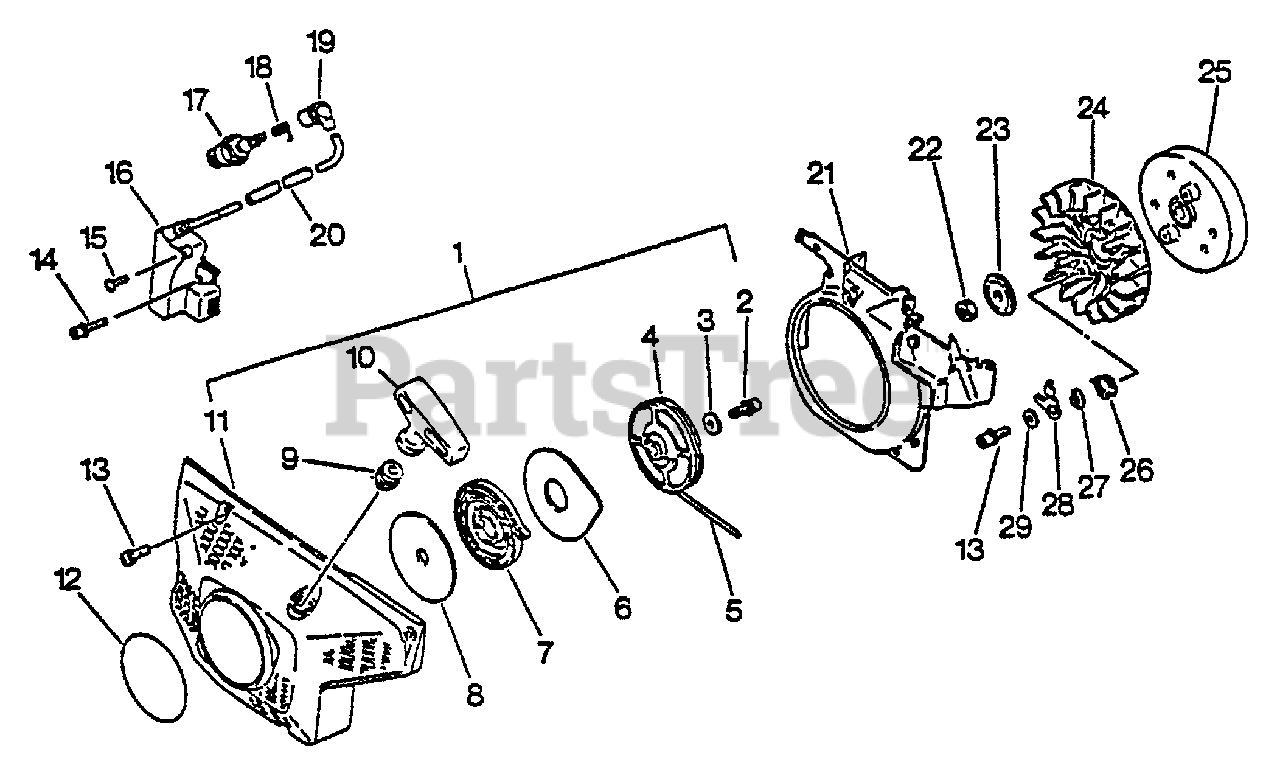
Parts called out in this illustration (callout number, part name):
1	STARTER ASSY
2	SCREW - 5X14
3	WASHER - 5
4	REEL, ROPE
5	ROPE, STARTER - 4X950
6	PLATE, STARTER
7	SPRING, REWIND
8	PLATE, STARTER
9	GUIDE, ROPE
10	GRIP, STARTER
11	CASE, STARTER
12	LABEL - ECHO
13	SCREW - 5X20
14	SCREW - 4X20
15	SCREW - 4X8
16	COIL, IGNITION
17	SPARK PLUG -- BPM-6A
18	TERMINAL, SPARK PLUG CAP
19	CAP, SPARK PLUG
20	TUBE
21	SHIELD, FAN
23	WASHER - CUP
25	FLYWHEEL
26	SPRING, RETURN
28	PAWL, STARTER
29	WASHER - 5
